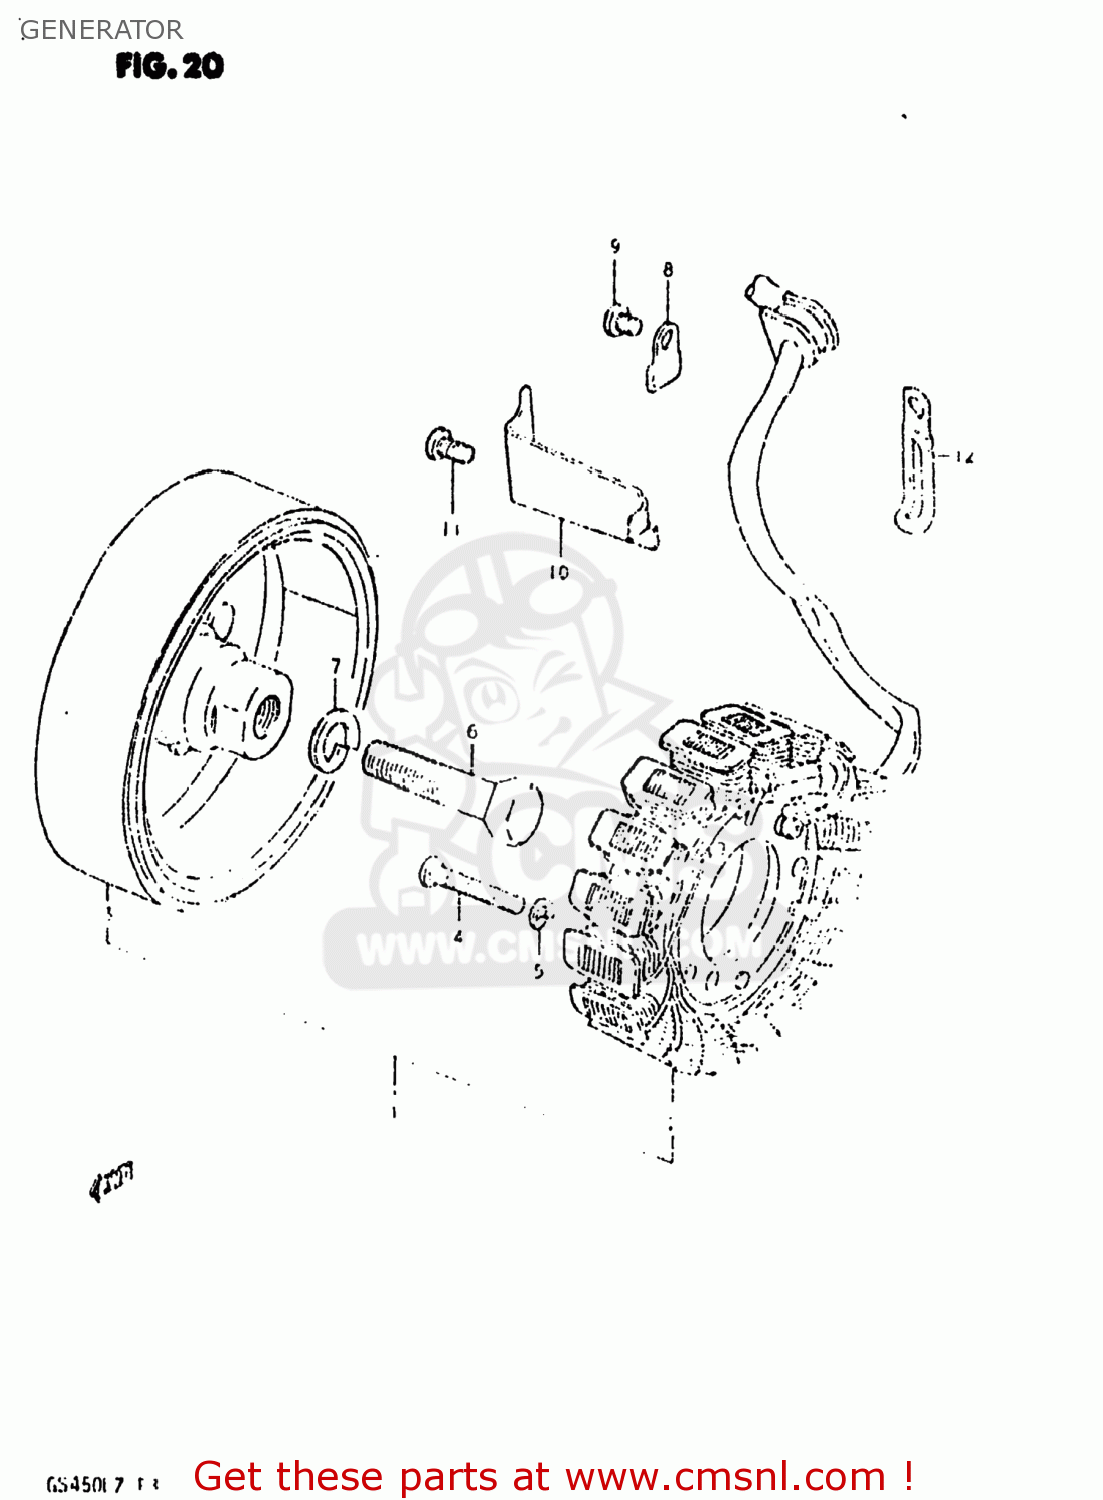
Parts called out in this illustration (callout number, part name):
1	GENERATOR ASSEMBLY
2	STATOR ASSEMBLY
3	ROTOR ASSEMBLY
4	SCREW
5	LOCK WASHER
6	BOLT 12X45
7	WASHER,LOCK 12
8	CLAMP,GENERATOR LEAD WIRE
9	SCREW
10	CLAMP,GENERATOR LEAD WIRE
11	SCREW
12	CLAMP L:35
